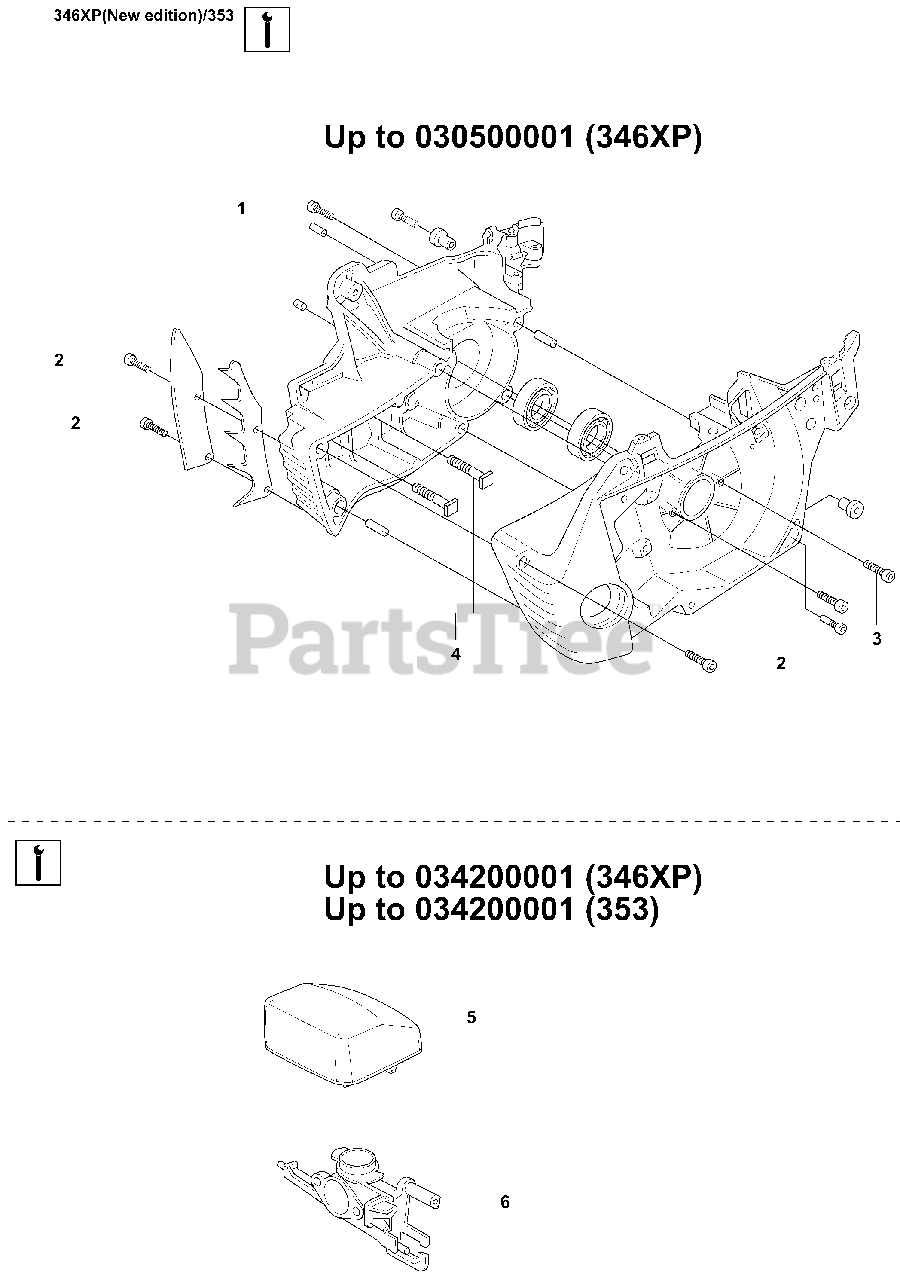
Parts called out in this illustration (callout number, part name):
1	SCREW
2	SCREW
3	SCREW
5	AIR FILTER - NYLON (B)
5	AIR FILTER - NYLON (Y)
5	AIR FILTER - FELT
